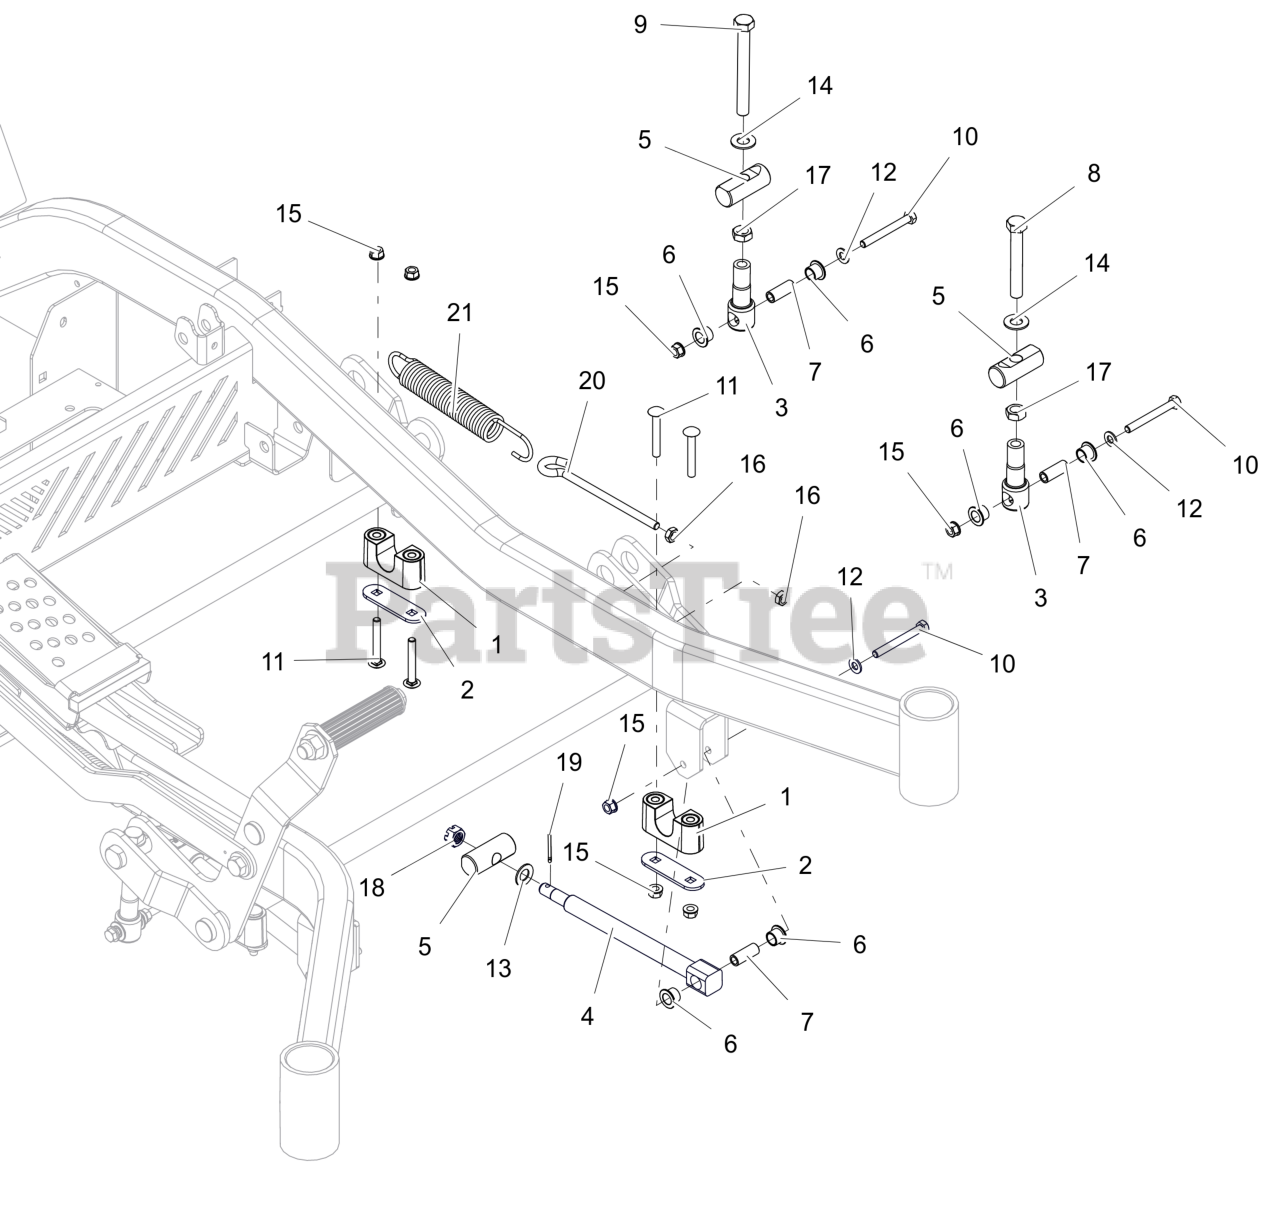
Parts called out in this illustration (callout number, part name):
1	ASM-BUSHING, DECK LIFT
2	PLATE, BEARING SUPPORT
3	LINK, DECK LIFT FORMED
4	DRAG,LINK-HD
5	PIN, DECK LIFT
6	BSHG, FLANGED .50X.625X.50X.062
7	SPCR, .31X.50X1.265
8	BLT, HEX .50-13X3.50F G5 ZCC
9	BLT, HEX .50-13X4.50F G8 ZCC
10	BLT, HEX .31-18X2.75 G5 ZCC
11	BLT, RHSSN.31-18X2.25 G5 ZCC
12	WSHR,FLT .344X.688X.065 ZCC
13	WSHR, BLVL .531 X 1.000 X .062 MZ
14	WSHR, FLT .557X1.040X.102 ZCC
15	NUT,LK-CTR-FLG .31-18 GF ZCC
16	NUT-JAM .375-16 G2 ZCC
17	NUT-JAM .500-13 G2 ZCC
18	NUT-SL .50-13
19	PIN,CTR.12X1.25EXTPRSQCT ZC120
20	BOLT,.38-16 X 5.25-.62 DIA EYE
21	SG-TENS .162X1.25X8.25 WLD 25
